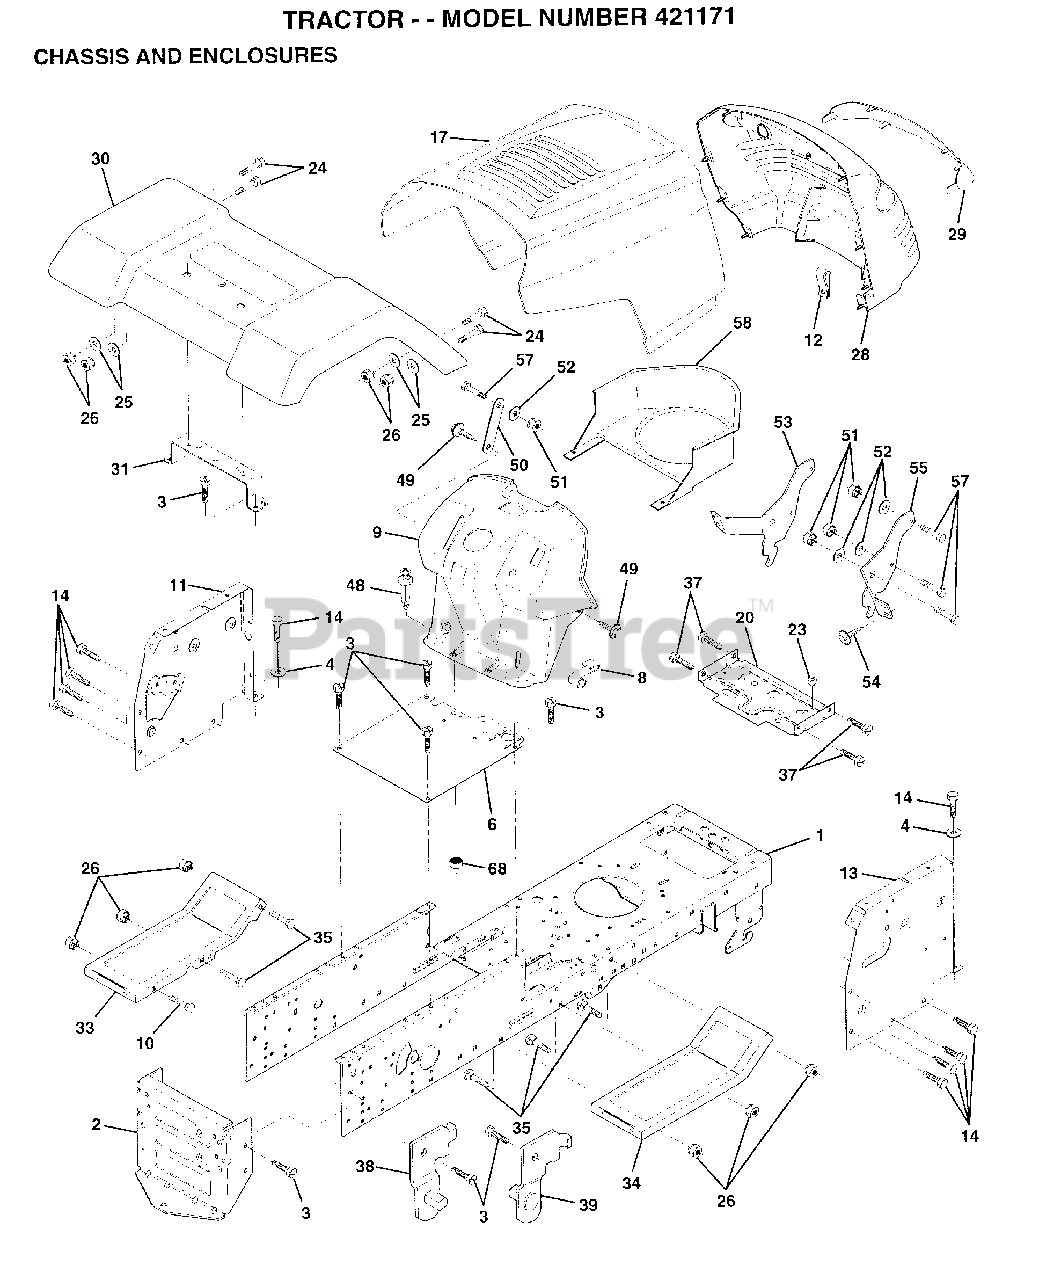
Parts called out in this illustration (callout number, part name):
1	CHASSIS WLDMT. 11GA.
3	SCREW
4	WASHER
8	"CLIP,INSULATOR"
11	PANEL.DASH.LH.
12	CLIP.TINNERMAN
13	PANEL.DASH.RH
14	PANEL.DASH.RH
14	SCREW LT
20	PLATE.MTG.BTRY.TK
24	BOLT
25	WASHER
26	NUT
28	GRILL.P/L.EURO.
29	LENS.EURO.W/DECAL
31	BRKT FENDER
33	FOOTREST.LH.LT/GT
34	FOOTREST.RH.LT/GT
35	BOLT
37	SCREW LT
38	BRACKET ASM LH
39	BRACKET ASM RH
48	RIVET.PUSH.PLATE
49	SCREW HEX CRT
50	BRACE SUPT DASH
51	NUT
52	WASHER
53	BRACKET.GRILLE.LH
55	BRACKET.GRILLE.RH
58	DUCT.AIR.B&S.18HP
68	NUT
